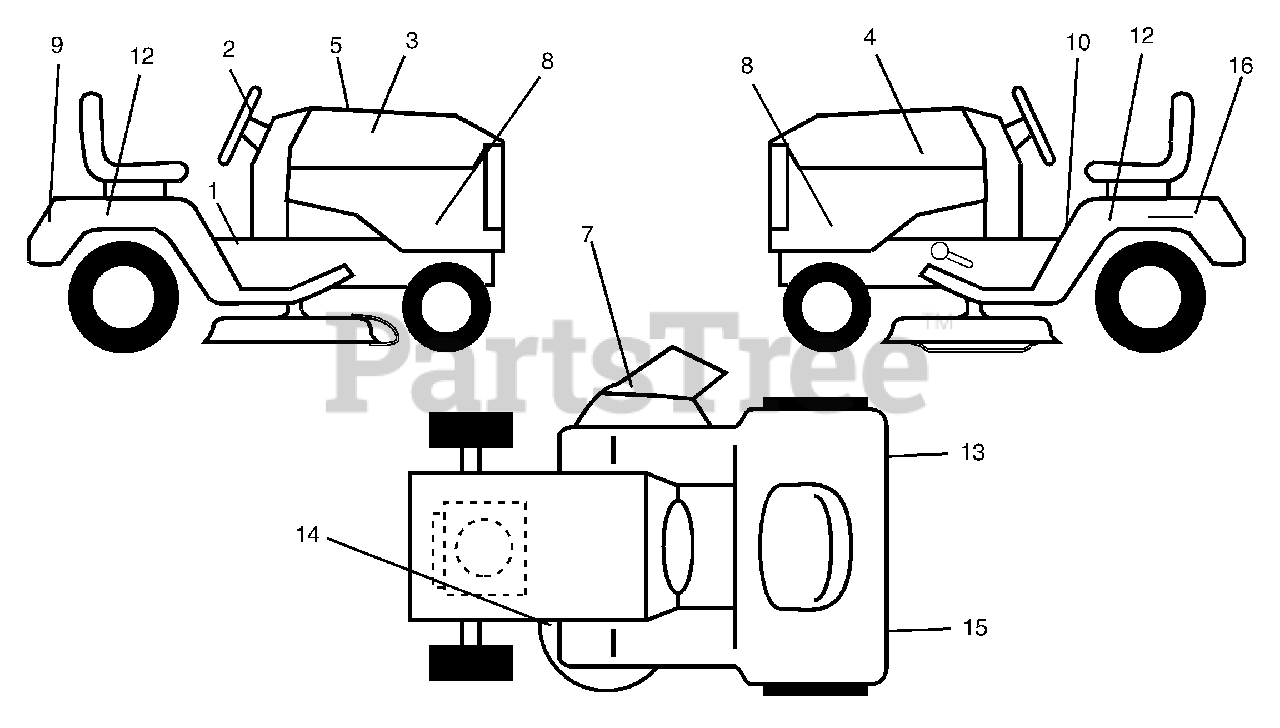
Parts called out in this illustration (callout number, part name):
1	Decal Instruction Operat English/French
2	Decal Ins Strg Wh
3	Decal Hood Rh
4	Decal Hood Lh
5	Decal Replacement
7	Decal Deck "B" 42"
8	Decal Hood Side Panel
9	Decal Fender Logo
10	Decal Danger English
12	Decal Fender
13	Decal Reflector LH
14	Decal V-belt Schematic 42"
15	Decal Reflector RH
16	Decal Battery Danger/Poison
20	Decal HP Engine
